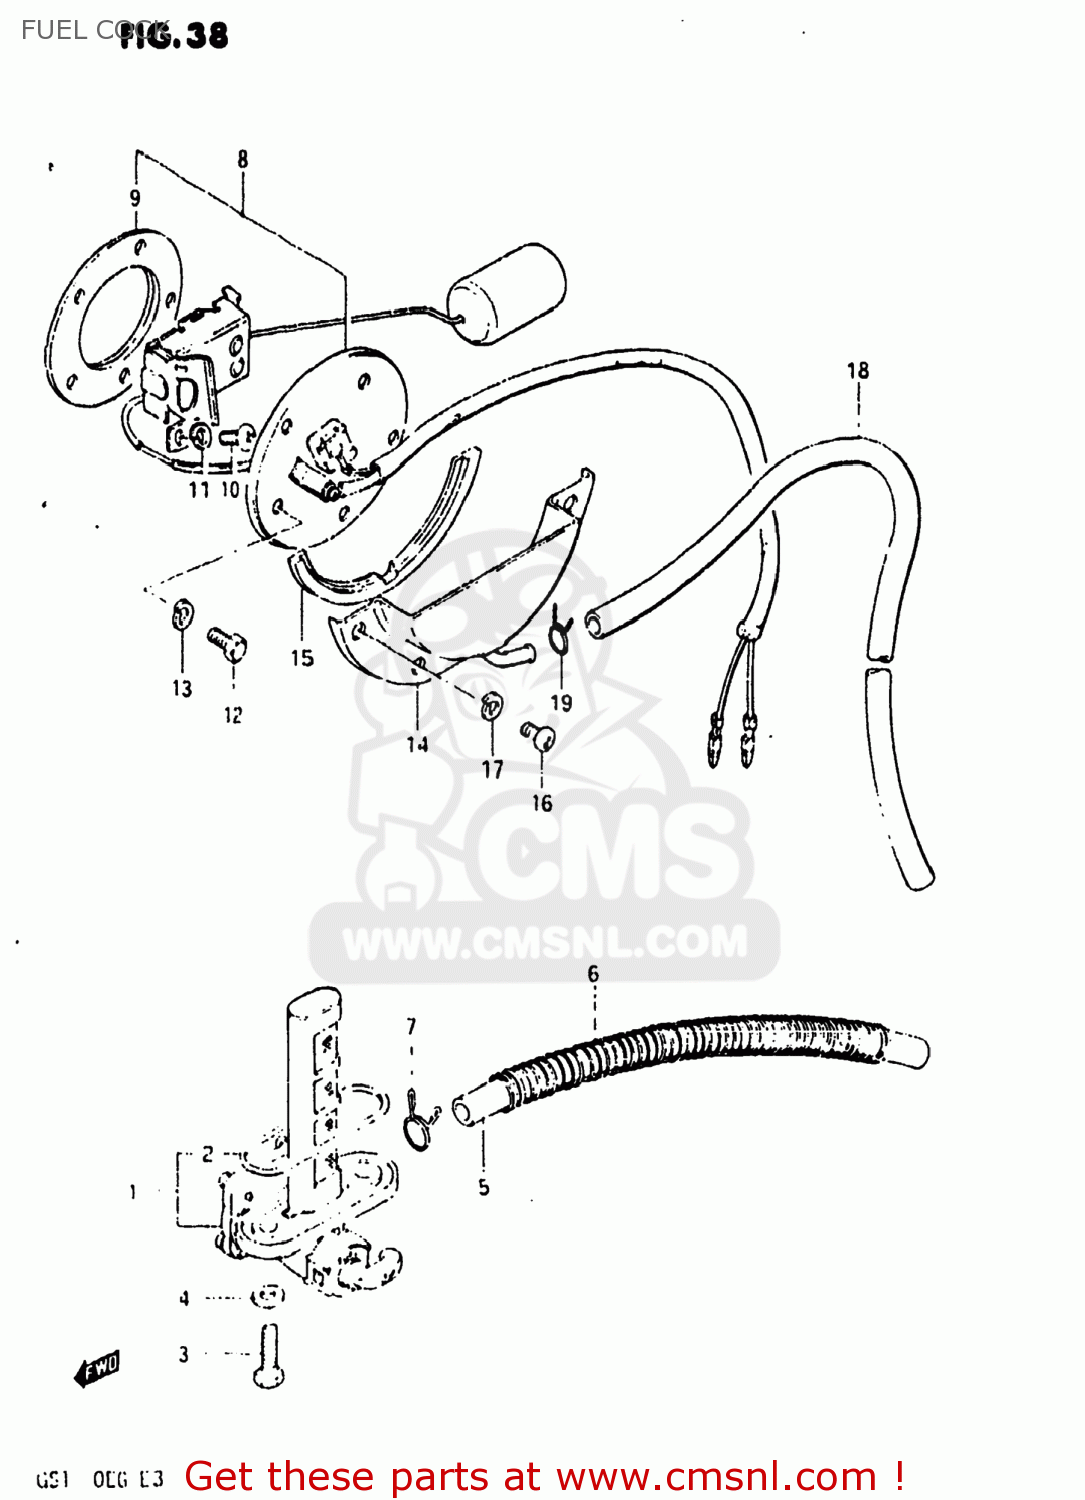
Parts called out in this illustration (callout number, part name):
1	COCK ASSY,FUEL
2	O RING
3	BOLT(6X20)
4	GASKET
5	HOSE
6	SPRING
7	CLIP
8	GAUGE ASSEMBLY,FUEL LEVEL
9	GASKET,FUEL LEVEL GAUGE (NAS)
10	SCREW 5X10
11	LOCK WASHER
12	BOLT
13	LOCK WASHER
14	PLATE,FUEL DRAIN
15	GASKET (NAS)
16	SCREW
17	LOCK WASHER
18	HOSE,FUEL
19	CLIP
